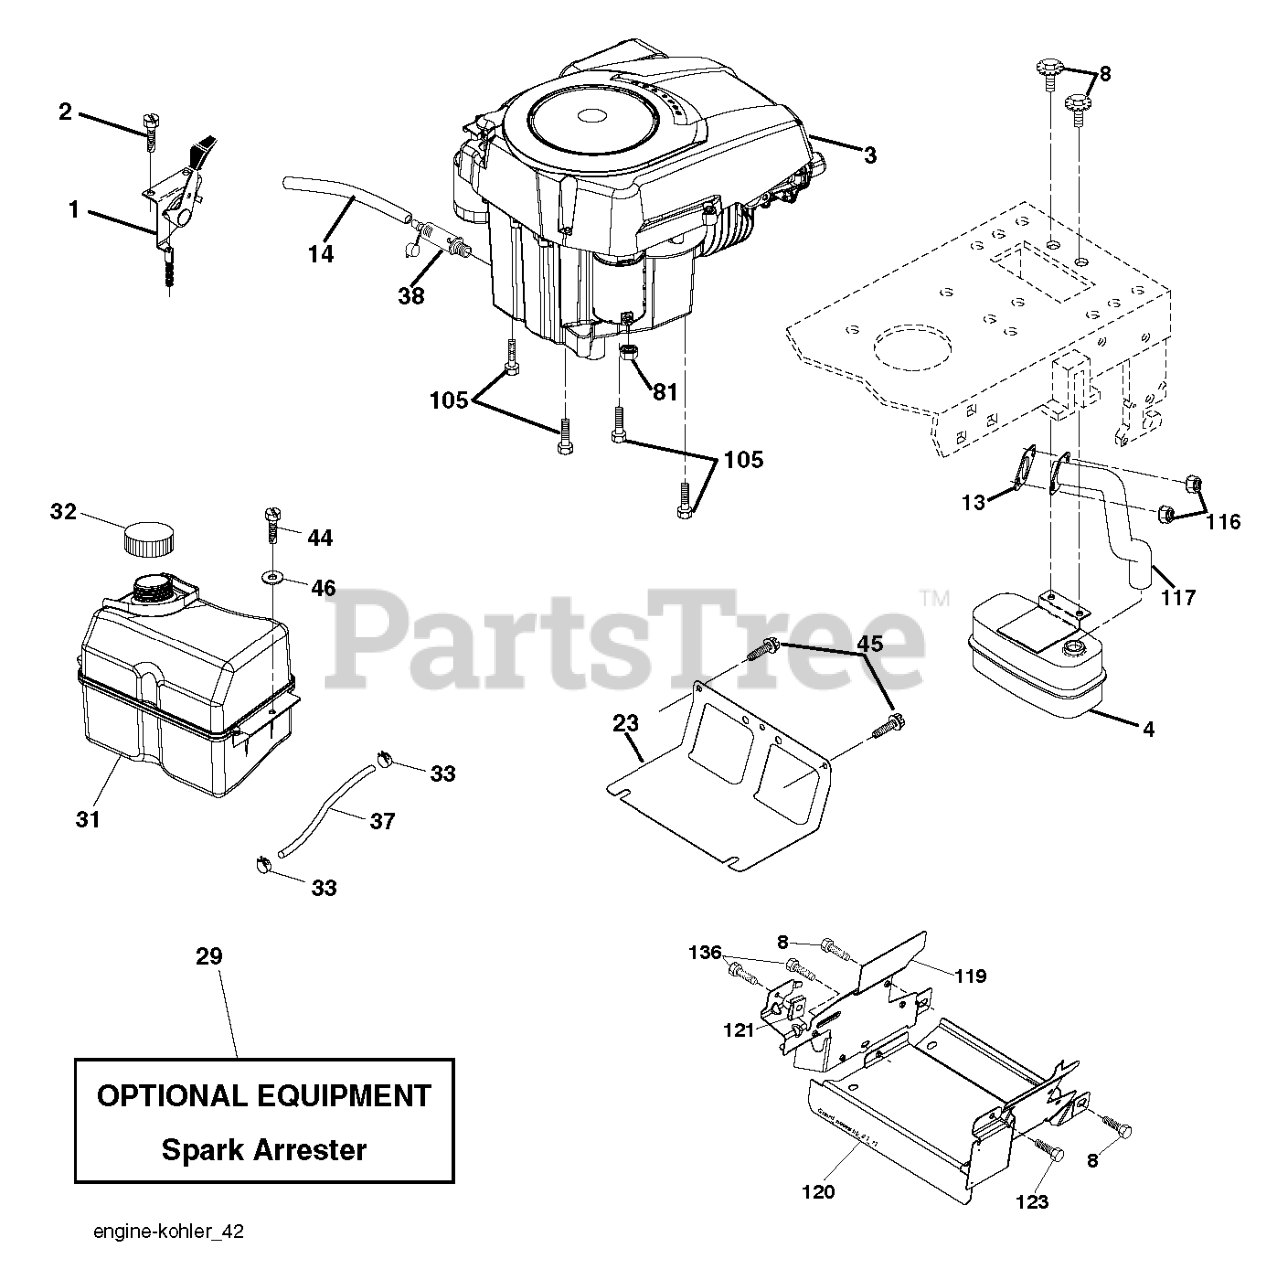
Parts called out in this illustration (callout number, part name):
1	CONTROL.TH/CK.C.
2	SCREW.#10 X 0.750.BOS
4	MUFFLER.SINGLE.CYL.KOHL/B&S
8	BOLT.5/16-18UNCX3/4 W/SEMS.BLK
13	GASKET.EXHAUST.KOHLER
14	TUBE, DRAIN OIL ASM.
23	SHIELD.BROWNING.DBR.GUARD
29	KIT.SPARK ARRESTOR 794945 B&S
31	RP TANK FUEL FRT 1.5 GAL
32	CAP ASM.FUEL.2.25"FR.
33	HOSE CLAMP
37	LINE.FUEL.20
38	VALUE.OIL.DRAIN
44	SCREW HEXWSHR 1/4-20X3/4
45	SCREW, 3/8-16X3/4
81	NUT
105	SCREW 3/8-16X1
116	NUT.HEX.FLANGE.TOPLOCK
117	RP.TUBE.EXHAUST.KOHL.COURAGE
119	LENKRAD
120	GUARD 532199767
123	SCREW, 5/16-18 X 1/2
136	SCREW.1/4-20X5/8
